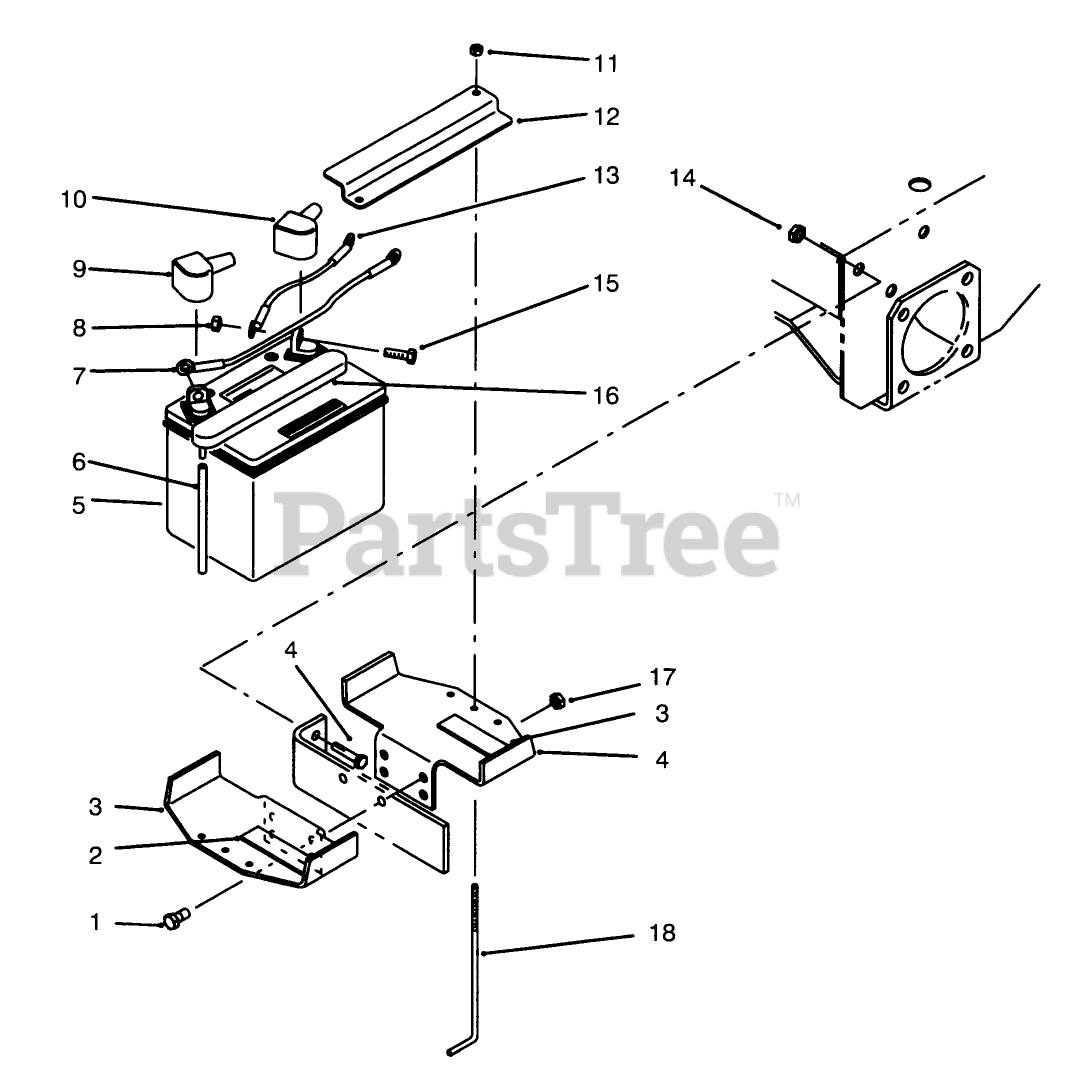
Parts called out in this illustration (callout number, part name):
1	SCREW-HH
2	PAD-TANK, FUEL
3	Battery
4	SCREW-HHF
5	Battery
6	TUBE-VENT
7	WIRE ASM
8	NUT-KEPS
9	BOOT-TERMINAL, BLACK
10	BOOT-TERMINAL, RED
11	NUT-LOCK, NI
12	Clamp-Battery
13	CABLE
14	NUT-HF
15	SCREW-HH
17	NUT-LOCK, NI
18	ROD-SUPPORT, BATTERY
